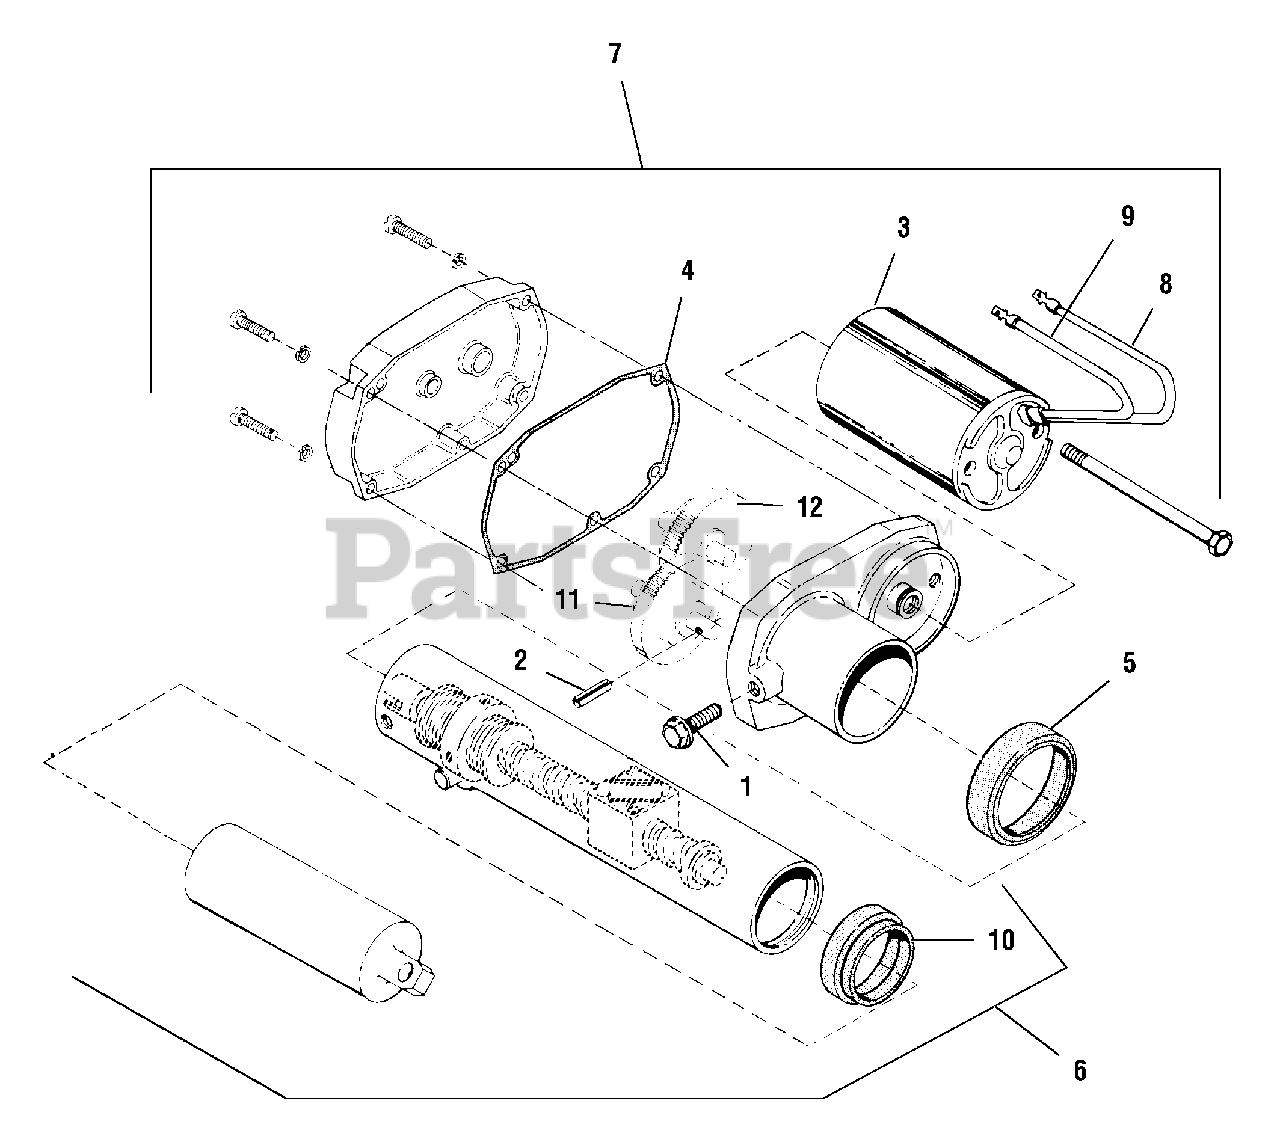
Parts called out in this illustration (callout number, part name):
1	CAPSCREW, Taptite
3	MOTOR KIT, 12 VDC
4	GASKET, Housing
5	SEAL, Outer Tube (Top)
6	TUBE & BALL SCREW ASSY.
7	MOTOR & GEARBOX ASSY., 12 VDC, 17:1 Ratio
8	BRUSH & LEAD (Red)
9	BRUSH & LEAD (Black)
10	SEAL, Inner Tube (Top)
11	OUTPUT GEAR & SLIP CLUTCH ASSY.
12	GEAR ASSY., 2nd & 3rd
